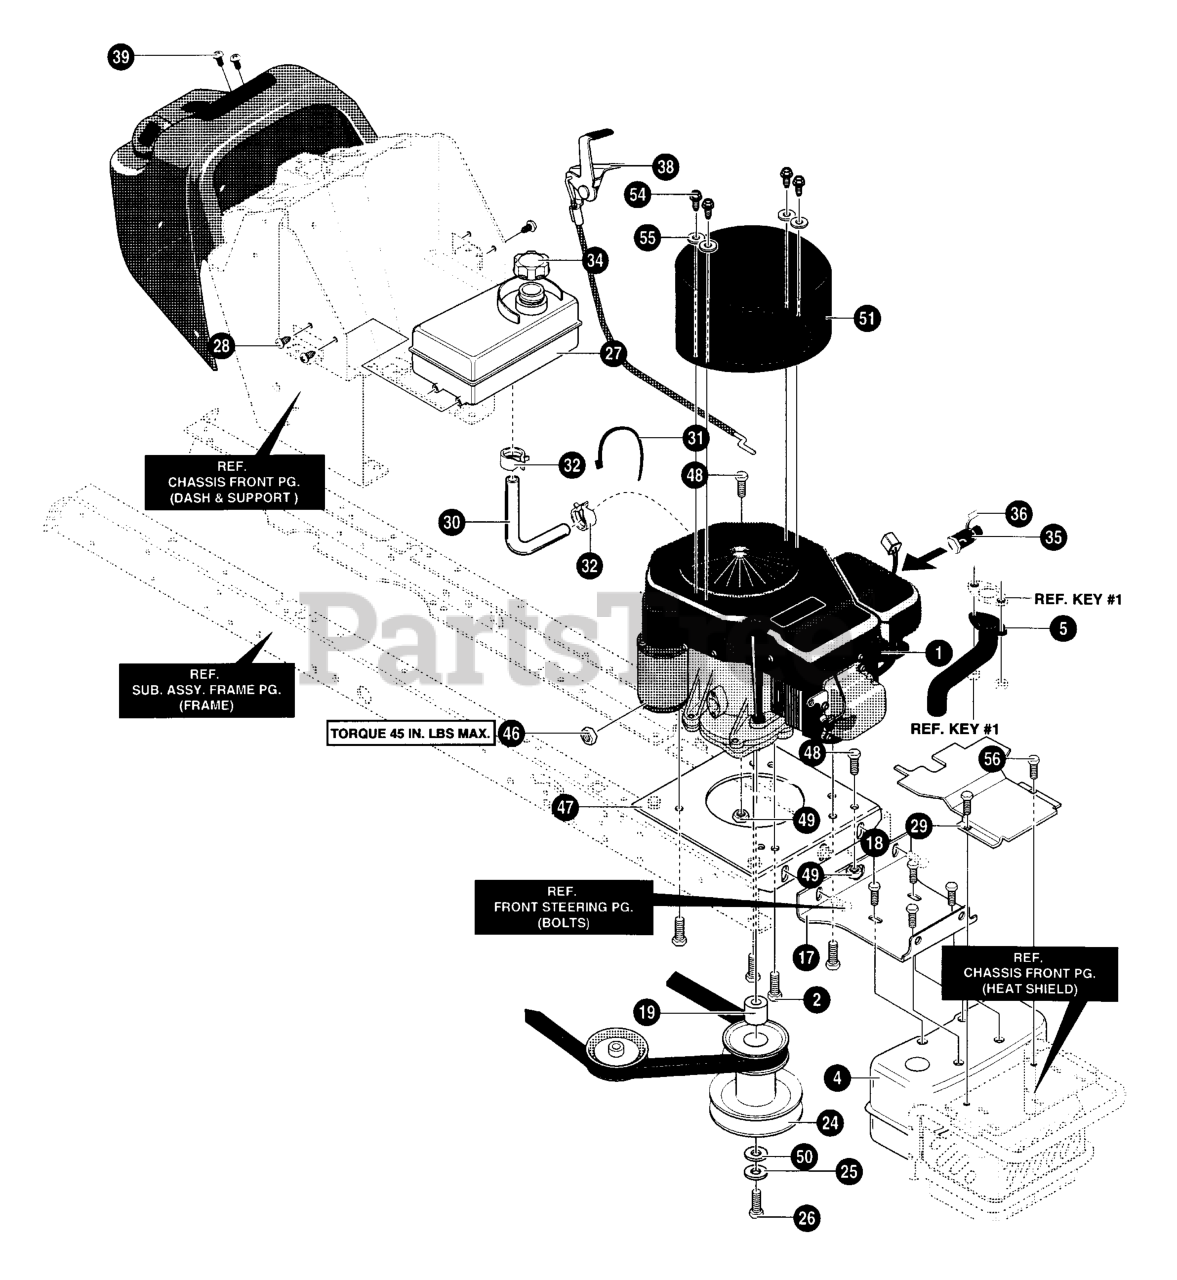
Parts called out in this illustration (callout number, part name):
1	ENGINE-15HP KOHLER
4	MUFFLER, SINGLE- CYLINDER
5	EXHAUST TUBE
17	BRACKET, MUFFLER MOUNT
19	SPACER, SLEEVE
24	PULLEY, STACK ASSY
27	TANK, FUEL 1.4 GAL.
29	HEAT SHIELD
30	LINK, FUEL
31	CABLE TIE
32	CLAMP, FUEL LINE
34	CAP, FUEL
35	OIL DRAIN
36	CAP, OIL DRAIN
38	THROTTLE CONTROL
39	SCREW, #8- 16X.50
46	NUT 1/4-20
47	PLATE, ENGINE
48	SCREW, 5/16-18 x 0.75
49	NUT, 5/16- 18
50	FLATWASHER
51	PLENUM, 15HP KOHLER
54	SCREW 10- 16X0.5
55	WASHER, FLAT
56	SCREW 1/4-20X0.63
